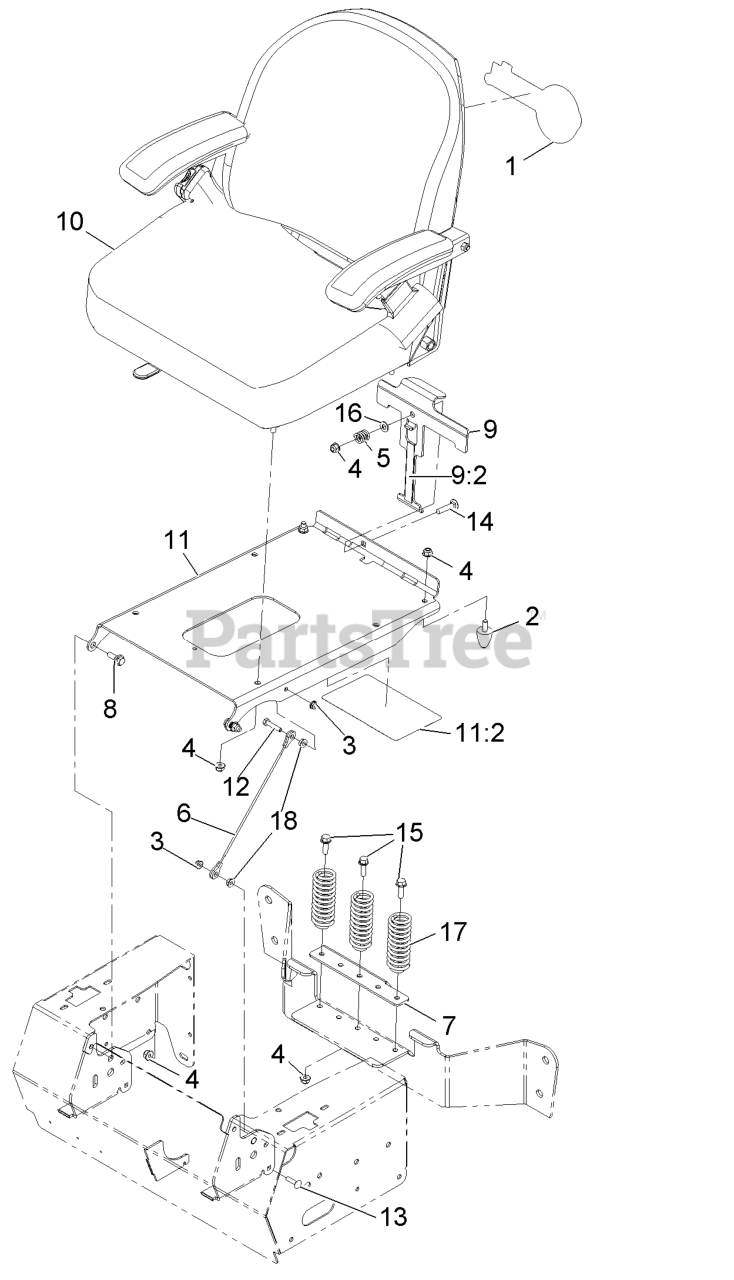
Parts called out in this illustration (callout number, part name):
1	DECAL,EXMARK LOGO
2	BUMPER-SEAT
4	NUT-HF, NI
5	SPRING-COMPRESSION
6	CABLE-STOP, SEAT
7	CATCH,SEAT LATCH
8	SCREW-SHOULDER
9	ASM-SEAT LATCH
9:2	STRIP-POLY WEAR
11	PLATE, SEAT W/DECALS
11:2	DECAL-SERVICE AID
12	SCREW-HH
13	SCREW-CARR
14	BOLT-CARR
15	SCREW-HHF
16	WASHER-PLAIN
17	SPRING-COMPRESSION
